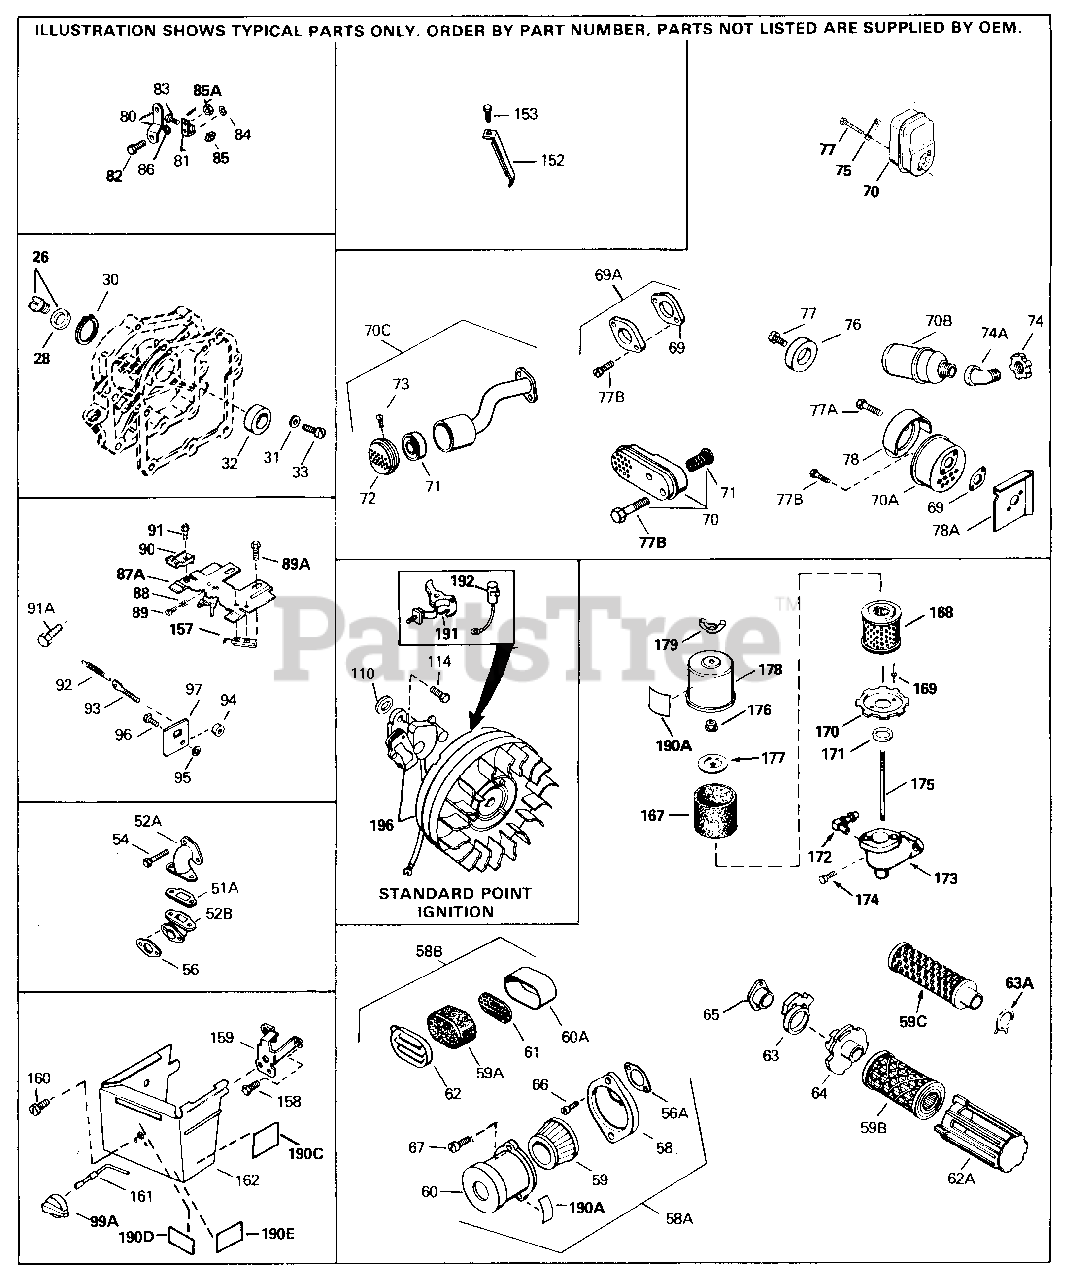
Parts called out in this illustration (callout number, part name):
26	Oil Fill Plug (Incl. 312) also availa ble in Packaged Part #740079
28	* Gasket, Oil fill plug
54	Screw, 1/4-20 x 1-7/32"
56	* Gasket, Carburetor to intake
56A	* Gasket, Carburetor to air cleaner
58	Bracket, Air cleaner
58A	Air Cleaner Ass'y. (Incl. 56A, 58, 59 , 60, 66, 67 & 170) (Use as required)
58A	Air Cleaner Ass'y. (Incl. 56A, 58, 59 , 60, 66, 67 & 170A) (Use as required )
58B	Air Cleaner Ass'y. (Incl. 56A, 59A, 6 0A, 61 & 62) (Use as required)
59	Air Filter (Paper) also available in Packaged Part #740029B
60	Body, Air cleaner
66	Screw, 10-32 x 1/2"
67	Screw, 8-32 x 3/8"
69A	Kit, Exhaust adapter (Incl. 69 & 77B) (Use as required) (Not for use on PT O side exhaust)
70	Muffler (Incl. 77B)
75	Plate, Lock
77B	Screw, 1/4-20 x 2-1/4"
80	Lever, Governor
81	Clamp, Governor lever
82	Screw, 8-32 x 5/16"
92	Extension Spring
93	Bolt, Governor spring adjusting
94	Nut, 10-32 lock
95	Lockwasher
96	Screw, 10-24 x 9/16"
97	Bracket, Governor adjusting bolt
114	Screw, Torx T-15, 10-24 x 1"
157	Terminal Ass'y. (Use as required)
161	Rod, Choke
